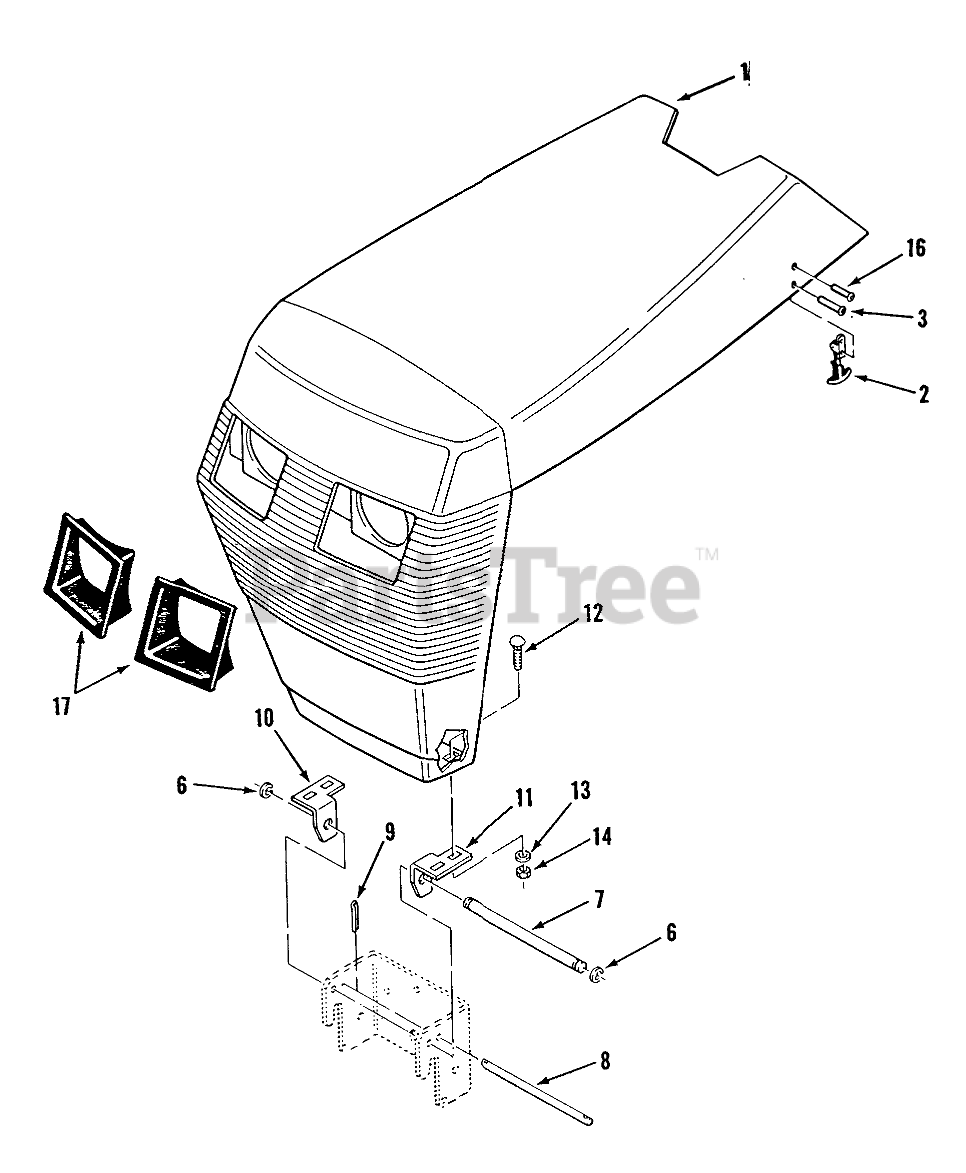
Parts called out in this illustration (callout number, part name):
1	Hood 516, 518 & 520-HC
2	Hood Latch (includes 109236 Handle Ass-y & 109237 Latch Keeper)
3	RIVET -4
6	RING-RETAINING
7	GRILL PIVOT ROD
8	ROD-HOOD STOP
9	Cotter Pin
10	BRKT-GRILL PIVOT R
11	BRKT-GRILL PIVOT R (NS)
12	Bolt-Carriage
14	Nut
16	RIVET
17	HEADLIGHT BEZEL ASSY.(SERVICE)
24	WASHER 5/16 SAE
